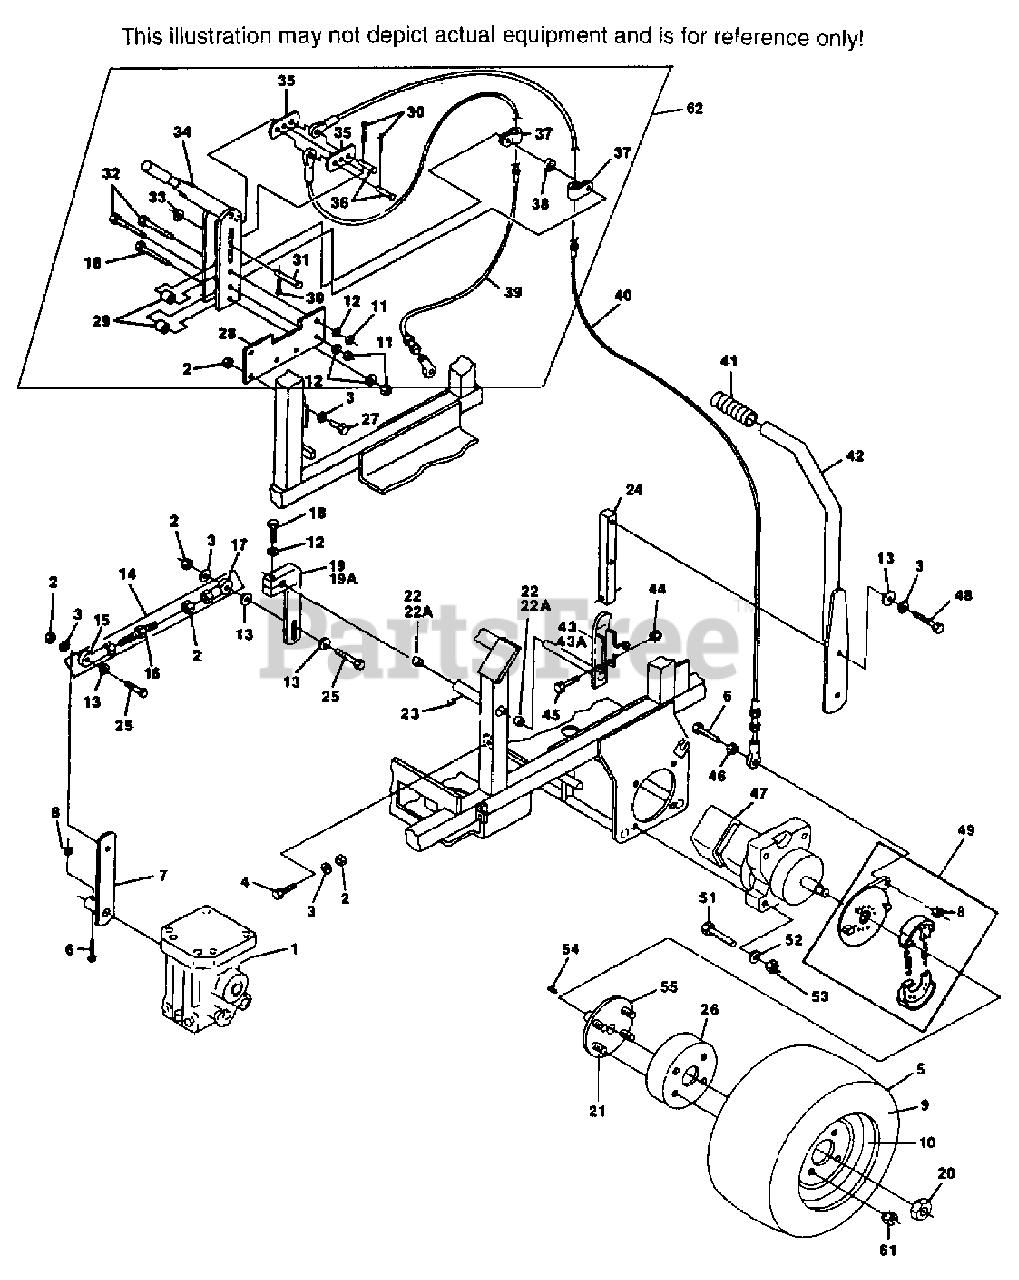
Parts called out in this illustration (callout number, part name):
1	PUMP, SUNDSTRAND
5	WHEEL ASSEMBLY
7	LEVER, PUMP CONTROL
8	HEX NUT, 1/4-20 ELASTIC STOP
9	TIRE ONLY
10	RIM ONLY
13	FLAT WASHER 3/8(.391 X .938 X .105)
14	TURNBUCKLE ASSEMBLY
15	BALL JOINT, LH THREAD
16	LINK, TURNBUCKLE
17	BALL JOINT, RH THREAD
19	LEVER, PUMP TRANSFER - RH
19A	LEVER, PUMP TRANSFER - LH
20	SPRING LOCK NUT
21	SERRATED BOLT, 1/2-20
22	BUSHING - LH
22A	BUSHING - RH
23	GREASE FITTING
24	BAR CONTROL LEVER
26	BRAKE DRUM
28	BRAKE EXTENSION BAR
29	SPACER
30	COTTER PIN
33	WASHER
34	BRAKE LEVER ASSEMBLY, COMPLETE
35	EQUALIZER
38	SPACER
39	BRAKE CABLE - RH
40	BRAKE CABLE - LH
41	GRIP, CONTROL HANDLE
42	CONTROL HANDLE
43	CONTROL LEVER - RH
43A	CONTROL LEVER - LH
44	HEX NUT, 5/16-18 ELASTIC STOP
47	MOTOR, WHITE
49	PARKING BRAKE ASSEMBLY
54	KEY, 5/16 X 5/16 X 15/16"
55	WHEEL HUB ASSEMBLY
61	LUG NUT, 1/2-20
